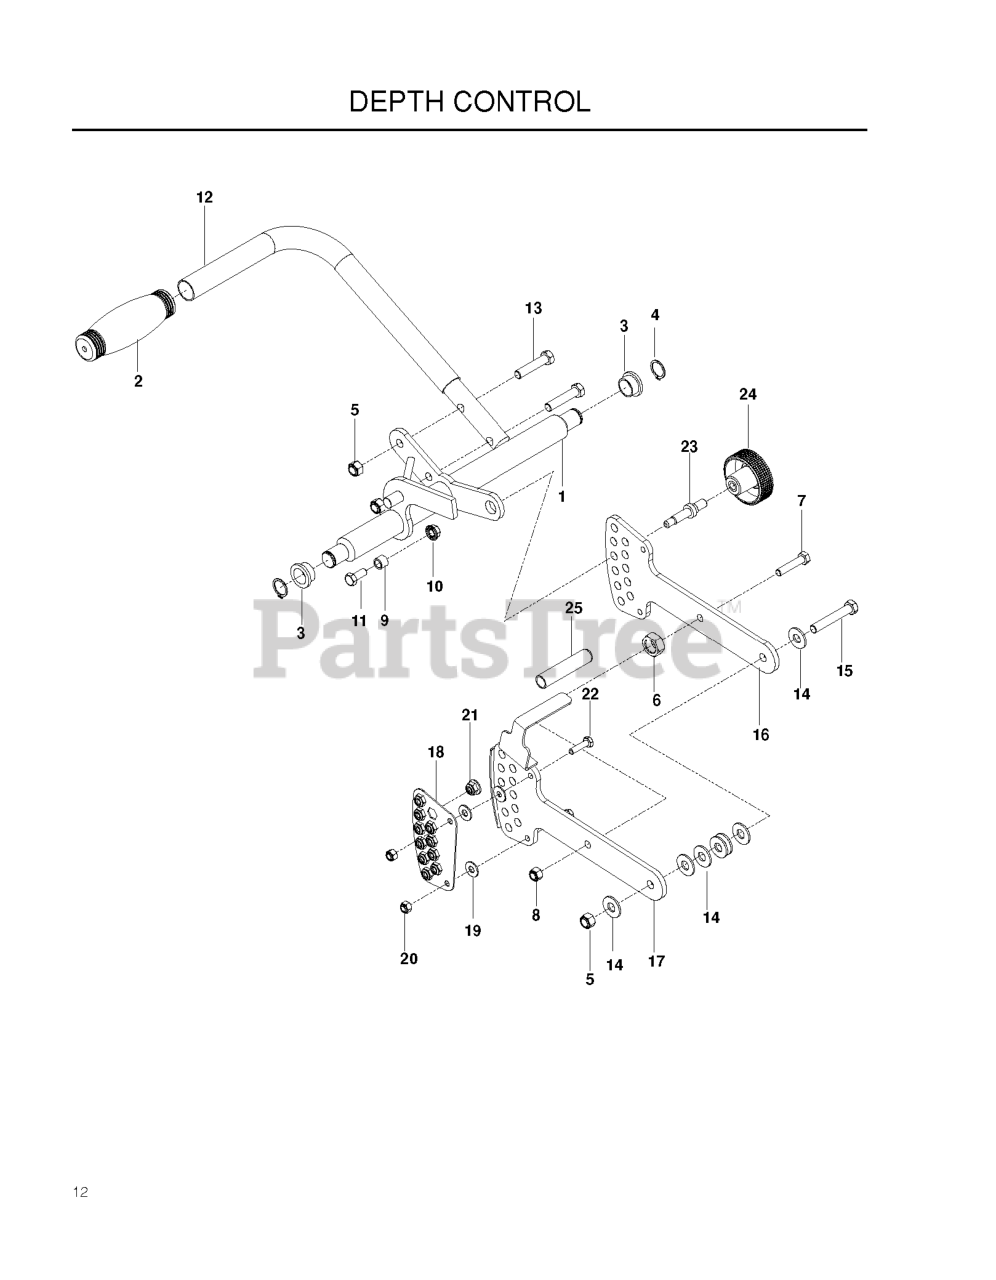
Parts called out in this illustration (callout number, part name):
1	RP.WLDMT-D.O.C. SHAFT, GREY
2	GRIP HANDLE
3	BEARING - FLANGE
4	SNAP RING - .75
5	NUT 3/8-16 NYLOC
6	NUT 5/8F HEX
7	CAPSCREW 5/16 X 1/1/2 HEX HEAD
8	NUT 5/16 NYLOC
10	NUT 5/16C WHIZ
11	HCS 5/16C X 3/4
12	HANDLE D.O.C. GREY
13	HCS 3/8-16 X 1 3/4 GR5
14	WASHER 3/8 FLAT
15	HCS 3/8C X 2 1/4
16	ADJUSTER D.O.C., GREY
17	ADJUSER WLDMT RH, GREY
18	PLATE-ADJUSTER NUT, GREY
19	WASHER 1/4 FLAT
20	NUT.1/4-20.HEX.NYLOC.ZD
21	5/16-18 NYLOC FLANGE NUT
22	HCS 1/4 X 1
23	ADJUSTER, STUD
24	KNOB
25	SCW 1/4-20 X 1-1/2 HEX
